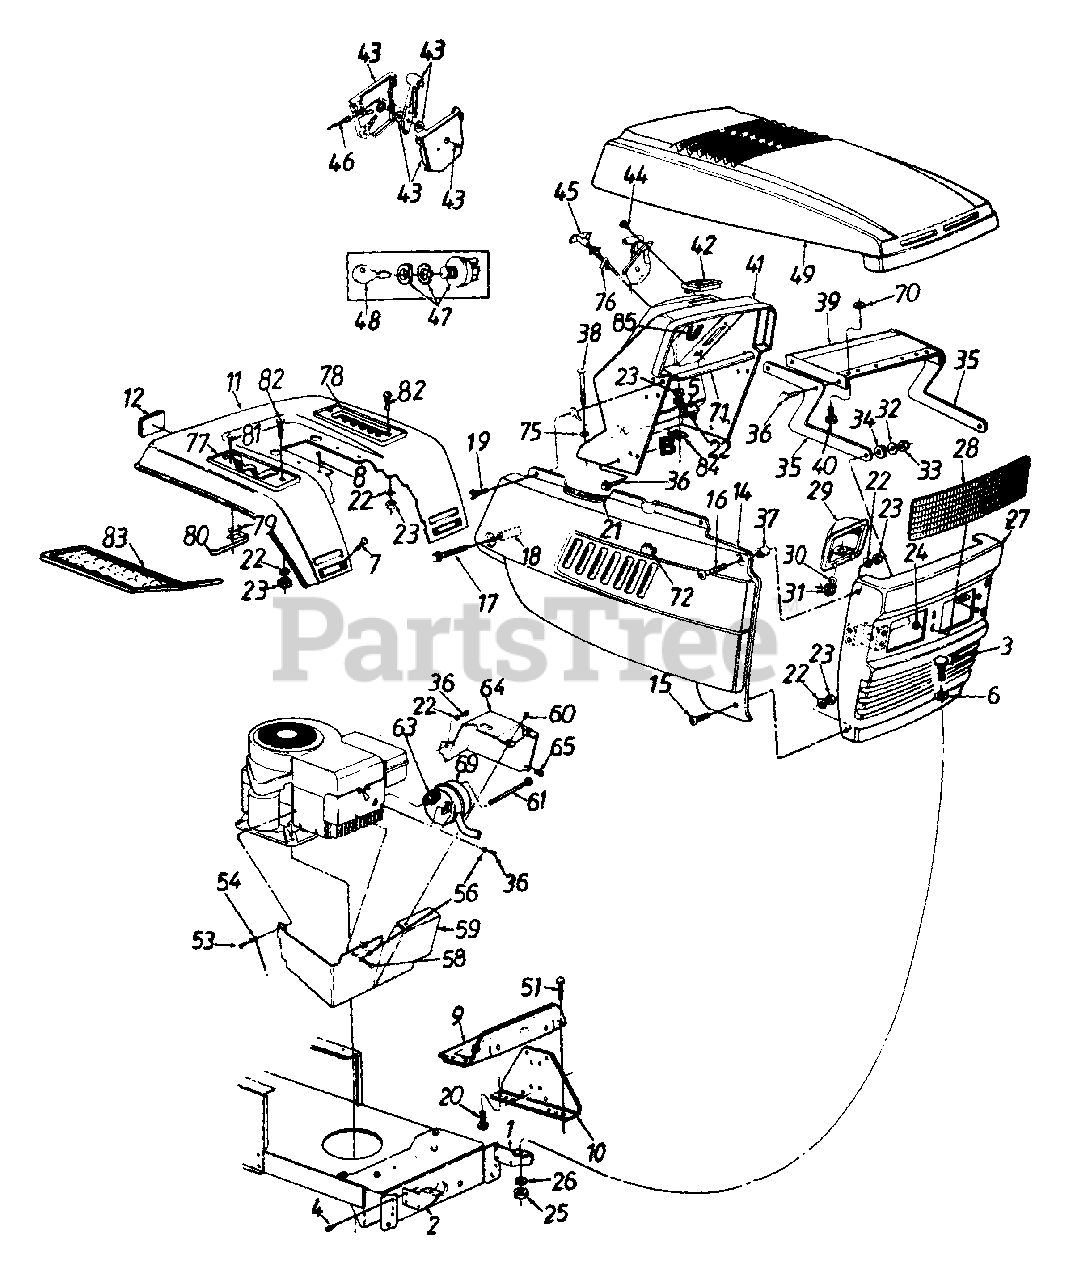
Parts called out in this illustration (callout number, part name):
1	Grille Mtg. Brkt.- L.H.
4	Hex Wash. Hd. Tap Scr. 5/16-18 x .5" Lg.
5	Light Switch
6	Fl-Wash. .344" I.D. x 1" O.D.
7	Carriage Bolt 1/4-20 x .5" Lg.
8	Hex Wash. Hd. Tap Scr. 5/16 x .75" Lg.
9	Support Bracket
14	Side Panel - R.H.
15	Truss Mach. Scr. 1/4-20 x .5" Lg.
16	Truss Mach. Scr. 1/4-20 x 1.0" Lg.
17	Hex Wash. TT-Tap Scr. 1/4-20 x 1.75" Lg.
18	Spacer .26" I D. x 1.32"
19	Hex Rolling Tap Scr. 1/4-20 x .75" Lg.
20	Hex Bolt 1/4-20 x .62" Lg.
21	Trim Strip - 12" Lg.
22	L-Wash. 1/4" I.D.
23	Hex Nut 1/4-20 Thd.
24	Speed Nut 5/16" Thd.
25	Hex Nut 5/16-18 Thd.
26	L-Wash. 5/16" I.D.
29	Headlamp Housing
30	Headlamp
31	Twist Lock Lamp Socket
32	Bell-Wash. .345" I.D. x .88"
33	Hex L-Nut 5/16-18 Thd.
34	Rubber Washer
35	Hood Hinge
36	Hex Wash. Hd. B-Tap Scr. 1/4-20 x .5" Lg.
37	Spacer .262" I.D. x .31"
38	Carriage Bolt 1/4-20 x 1.25" Lg.
41	Dash
42	Ammeter
43	Throttle Control Box Ass'y.
44	Mach. Scr. #10 x .44" Lg.
45	Choke Control
46	Throttle Control Wire
47	Ignition Switch
48	Ignition Key
51	Hex Wash. Hd. B-Tap Scr. 5/16-18 x .5" Lg.
53	Truss Mach. Scr. 5/16-18 x .75" Lg.
54	Ground Wire
56	Spr. Wash. 1/4" I.D.
58	Hex Bolt 1/4-20 x 3/8" Lg.
59	Muffler Heat Shield - Front
60	Hex AB-Tap Scr. #10 x .5" Lg.
61	Shoulder Bolt
63	Exhaust Gasket
64	Muffler Heat Shield - L.H.
65	Speed Nut #10-24 Thd.
69	Muffler
70	Fl-Wash. .406" I.D. x .812" O.D.
71	Grille Support Tube
75	Retaining Nut
76	Choke Retainer
77	Forward/Reverse Index Brkt.
78	7-Speed Index Brkt.
79	Insulator Nut Plate
80	Reverse Safety Switch
81	Hex Wash. Hd. AB-Tap Scr. #8 x .5" Lg.
82	Truss Mach. Scr. 1/4-20 x .75" Lg.
83	Rubber Foot Pad - L.H.
84	Dash Fastening Tab
85	Cable Tie
